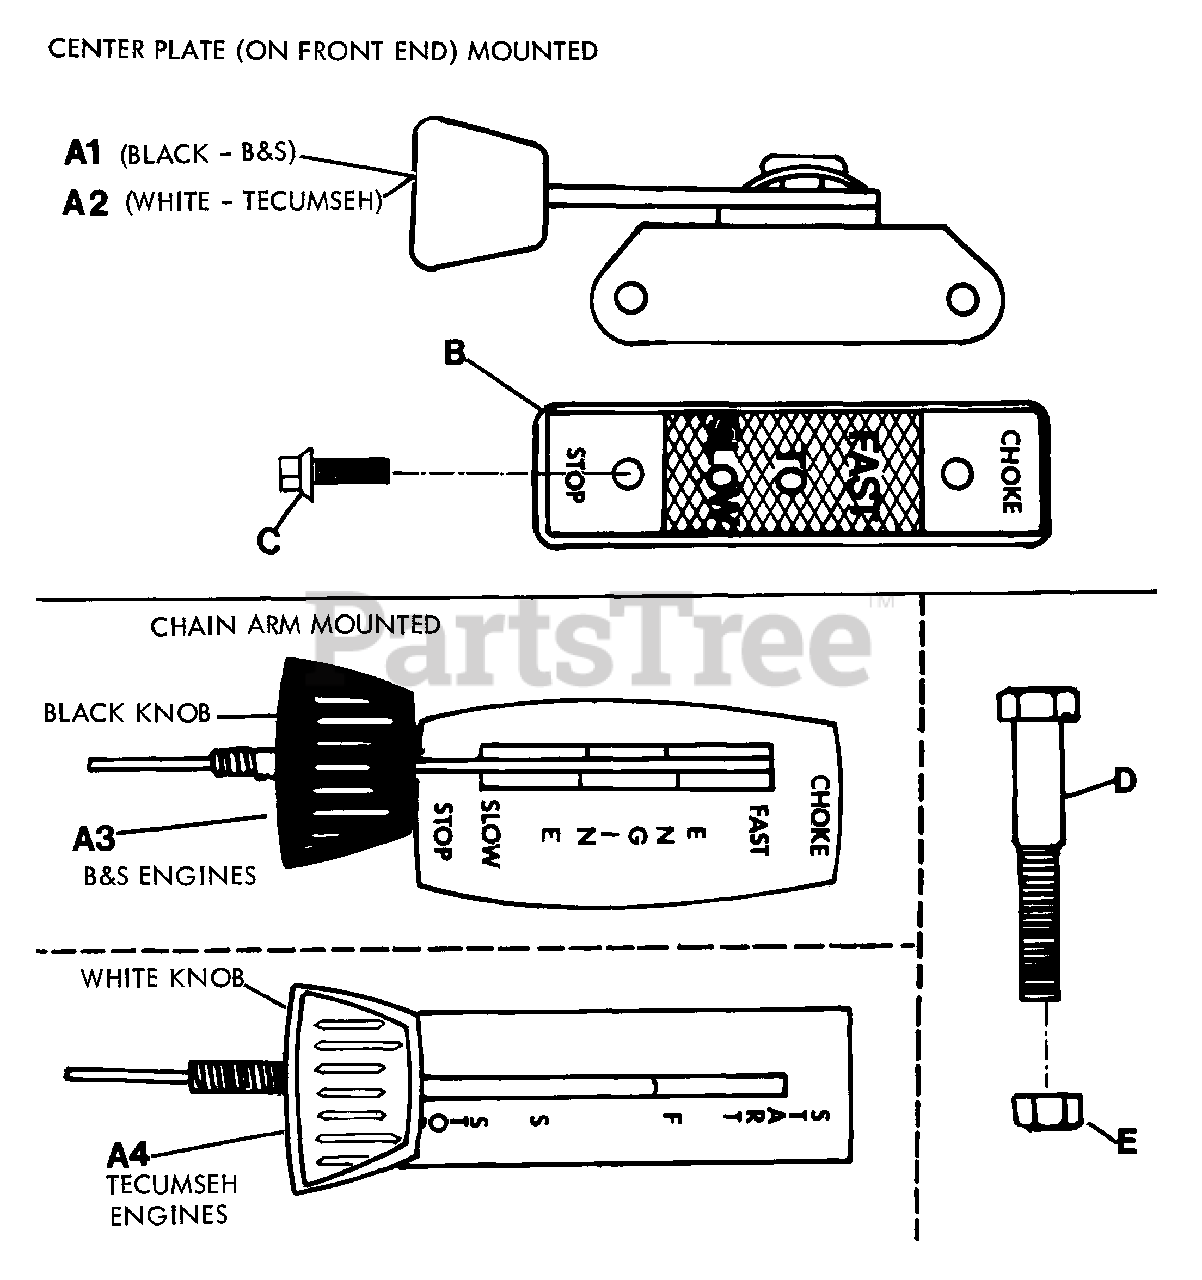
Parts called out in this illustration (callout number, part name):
A1	CONTROL, THROTTLE - BRIGGS (CABLE APPROX. 52" LONG)
A2	CONTROL, THROTTLE - TECUMSEH (CABLE APPROX. 57" LONG)
A3	CONTROL, THROTTLE - BRIGGS (CABLE APPROX. 14" LONG)
A4	CONTROL, THROTTLE - TECUMSEH (CABLE APPROX 17" LONG)
B	PLATE, THROTTLE (USED WITH A1 & A2)
C	SCREW, #10-24 x 1/2" Hex Washer Self-Tap (Torx)
D	SCREW, HEX HEAD CAP 1/4F x 1 -1/2
E	NUT, 1/4F HEX LOCK
